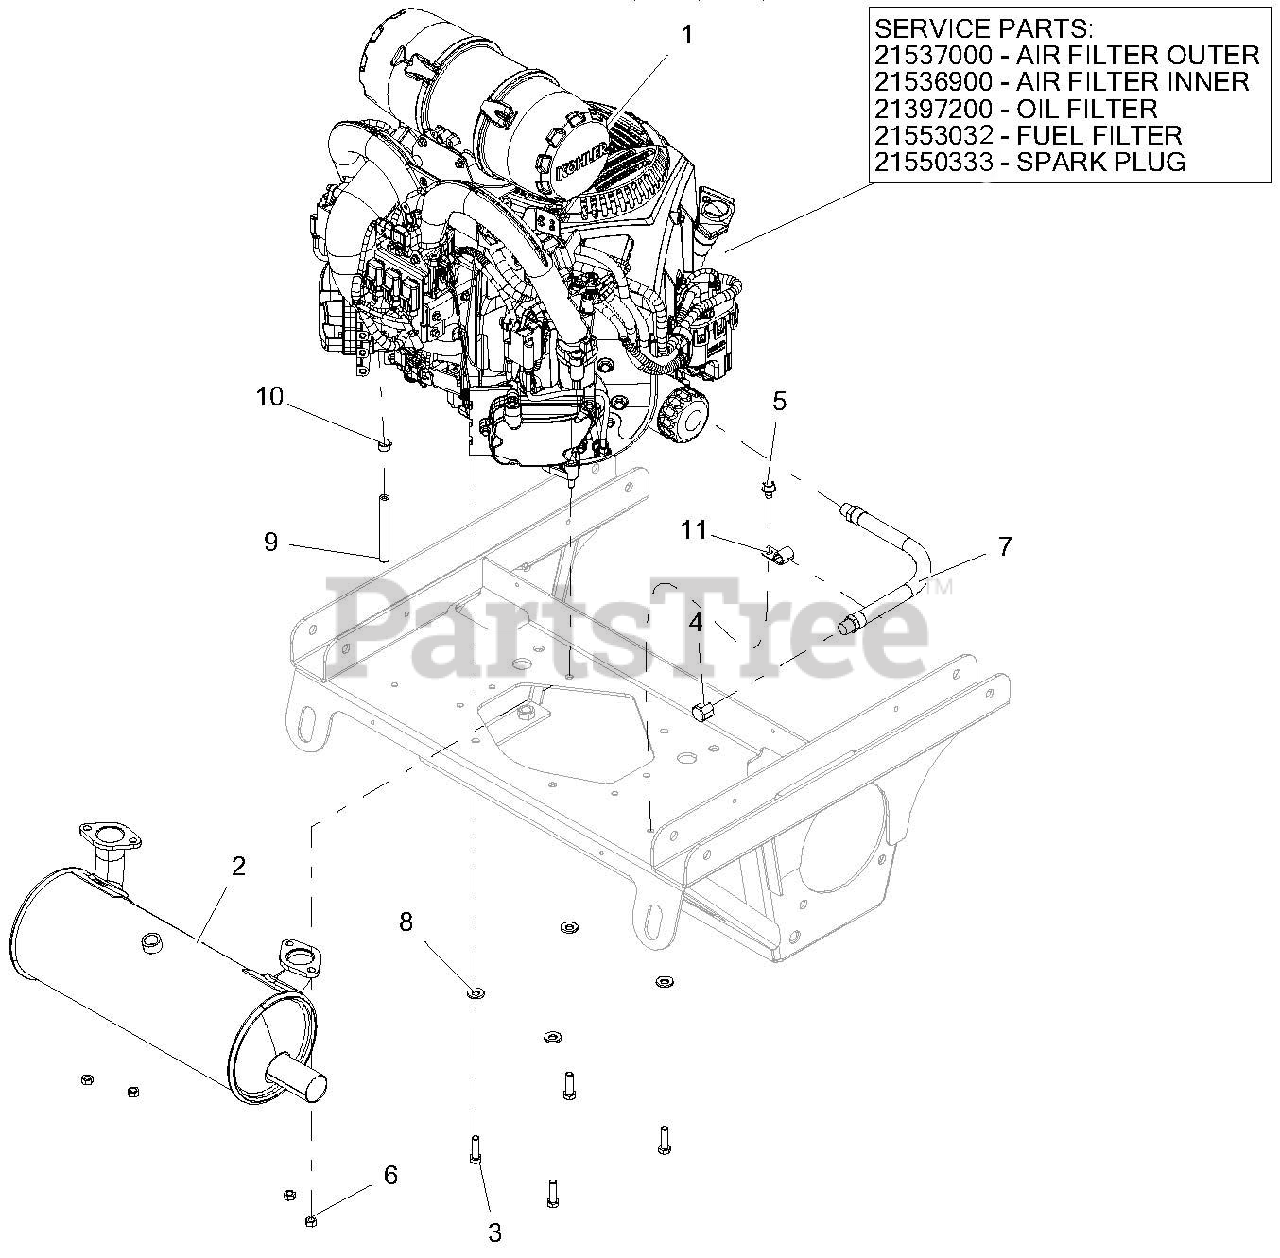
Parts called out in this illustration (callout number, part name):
1	ENGINE, KOHLER EFI
1	AIR FILTER OUTER
1	AIR FILTER INNER
1	OIL FILTER
1	FUEL FILTER
1	SPARK PLUG
2	MUFFLER, KOHLER EFI
3	BLT-HEX .38-16X1.25 GR5 YWZC NYTORQ
4	PIPE, CAP 3/8 NPT FEMALE
5	SCR-TAP .38-16X.50 HWH TR YWZ
6	NUT-LK-TOP M8-1.25 YWZC
7	HOSE, HYD .38-11-OK M6N0-M6N0
8	WSHR, 3/8" SPRING DISC
9	.25 LOW-PERM GAS HOSE 19.0" LG
10	CLAMP, FUEL LINE
